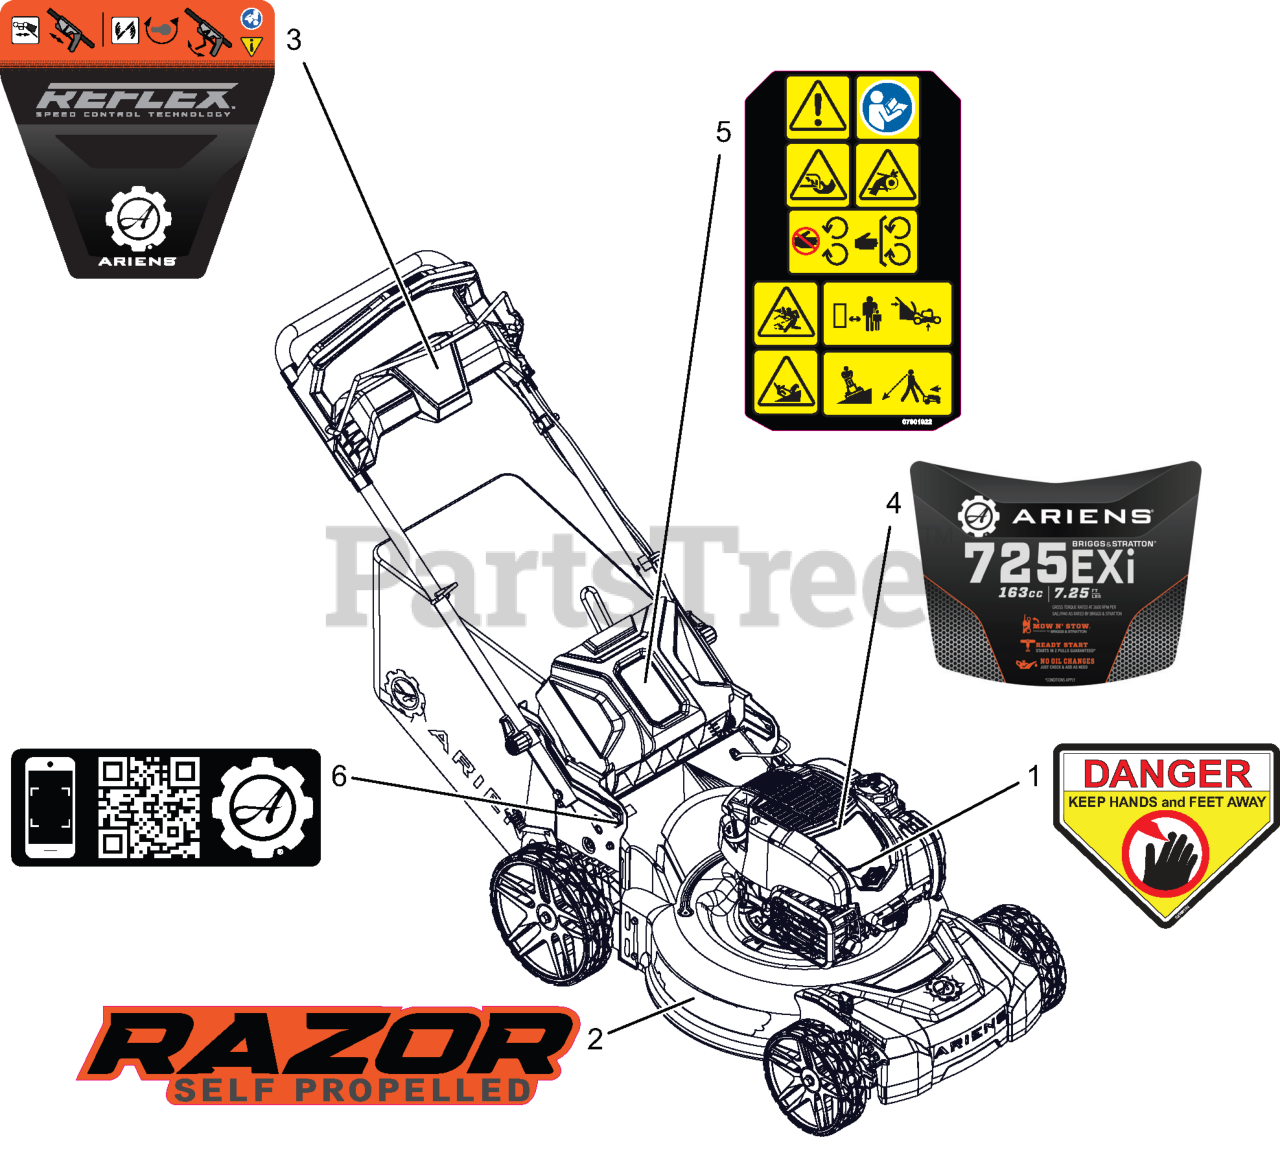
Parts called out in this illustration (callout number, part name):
1	DECAL, DANGER
2	DECAL, ARIENS SP
3	DECAL, ARIENS REFLEX CONTROL
4	DECAL, ENGINE 163CC - MNS
5	DECAL, MAIN SAFETY - WALK
6	DECAL, RAZOR QR
